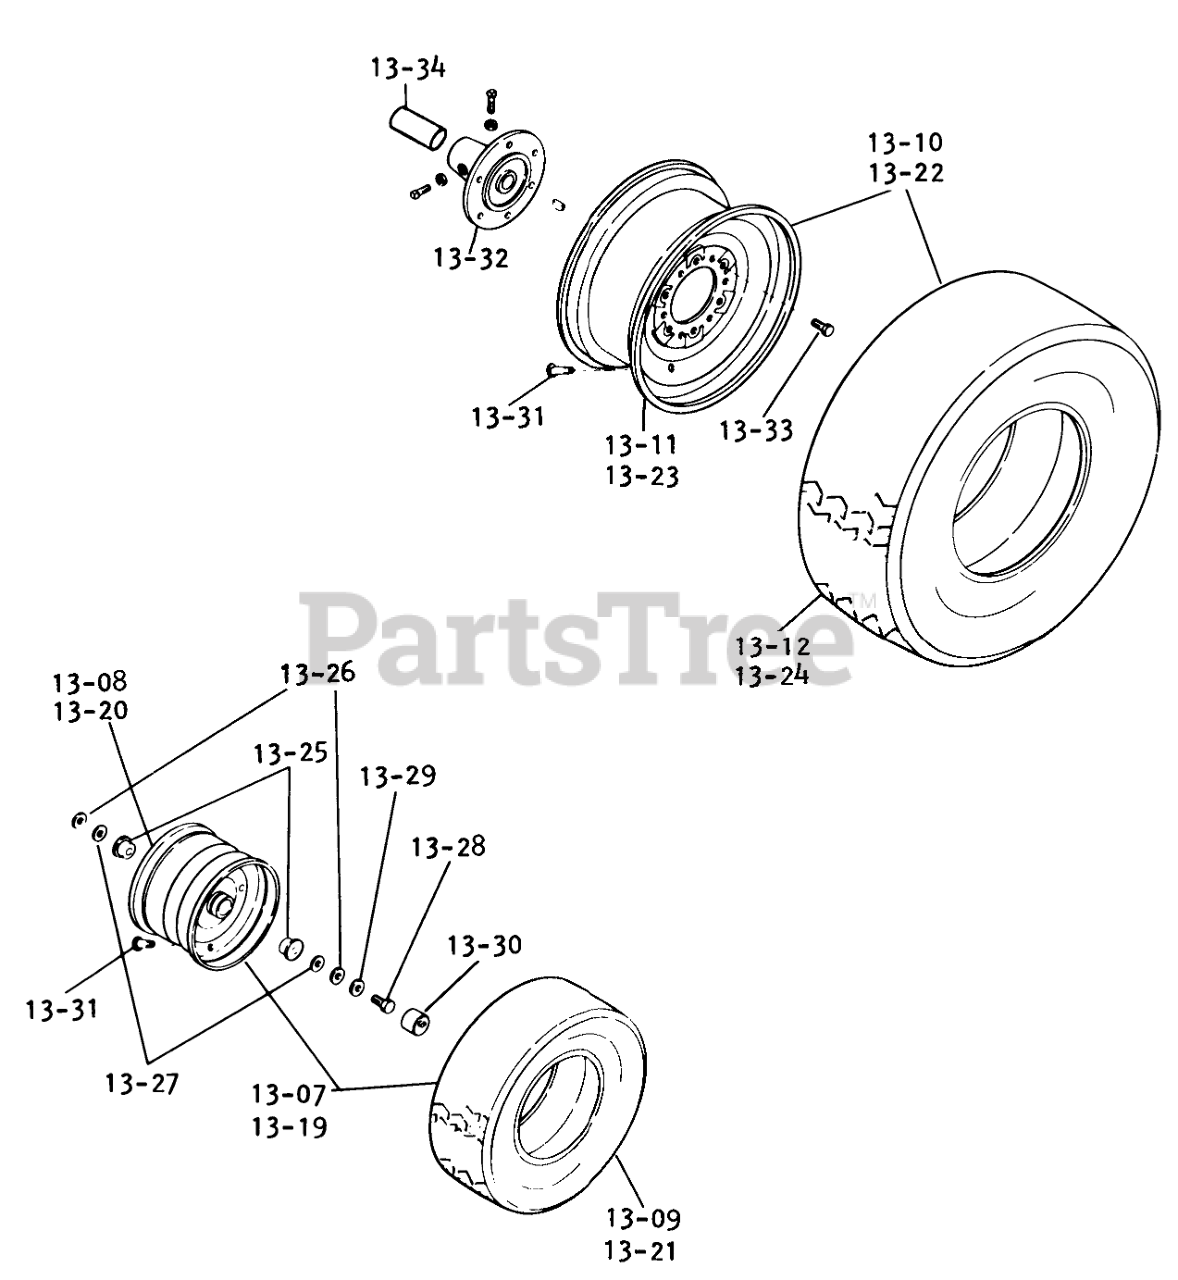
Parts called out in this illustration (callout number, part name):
13-07	ASSY-WHEEL
13-08	Wheel
13-09	Tire 18 X 850-8 Staight Rib
13-10	Rear Wheel & Tire Turf
13-11	Wheel 12 x 10.5 PC
13-12	Tire, Extra Width Traction
13-19	ASSY-WHEEL
13-20	Wheel
13-21	Tire 18 X 850-8 Staight Rib
13-22	Rear Wheel & Tire Cleat
13-23	Wheel 12 x 10.5 PC
13-24	Tire, Extra Width Cleat
13-25	BEARING WHEEL
13-27	Washer
13-28	Bolt
13-29	WASHER
13-30	HUBCAP
13-31	VALVE
13-32	REAR HUB R
13-33	LUG BOLT WHEEL 7/162
13-34	Axle Cover Tube
